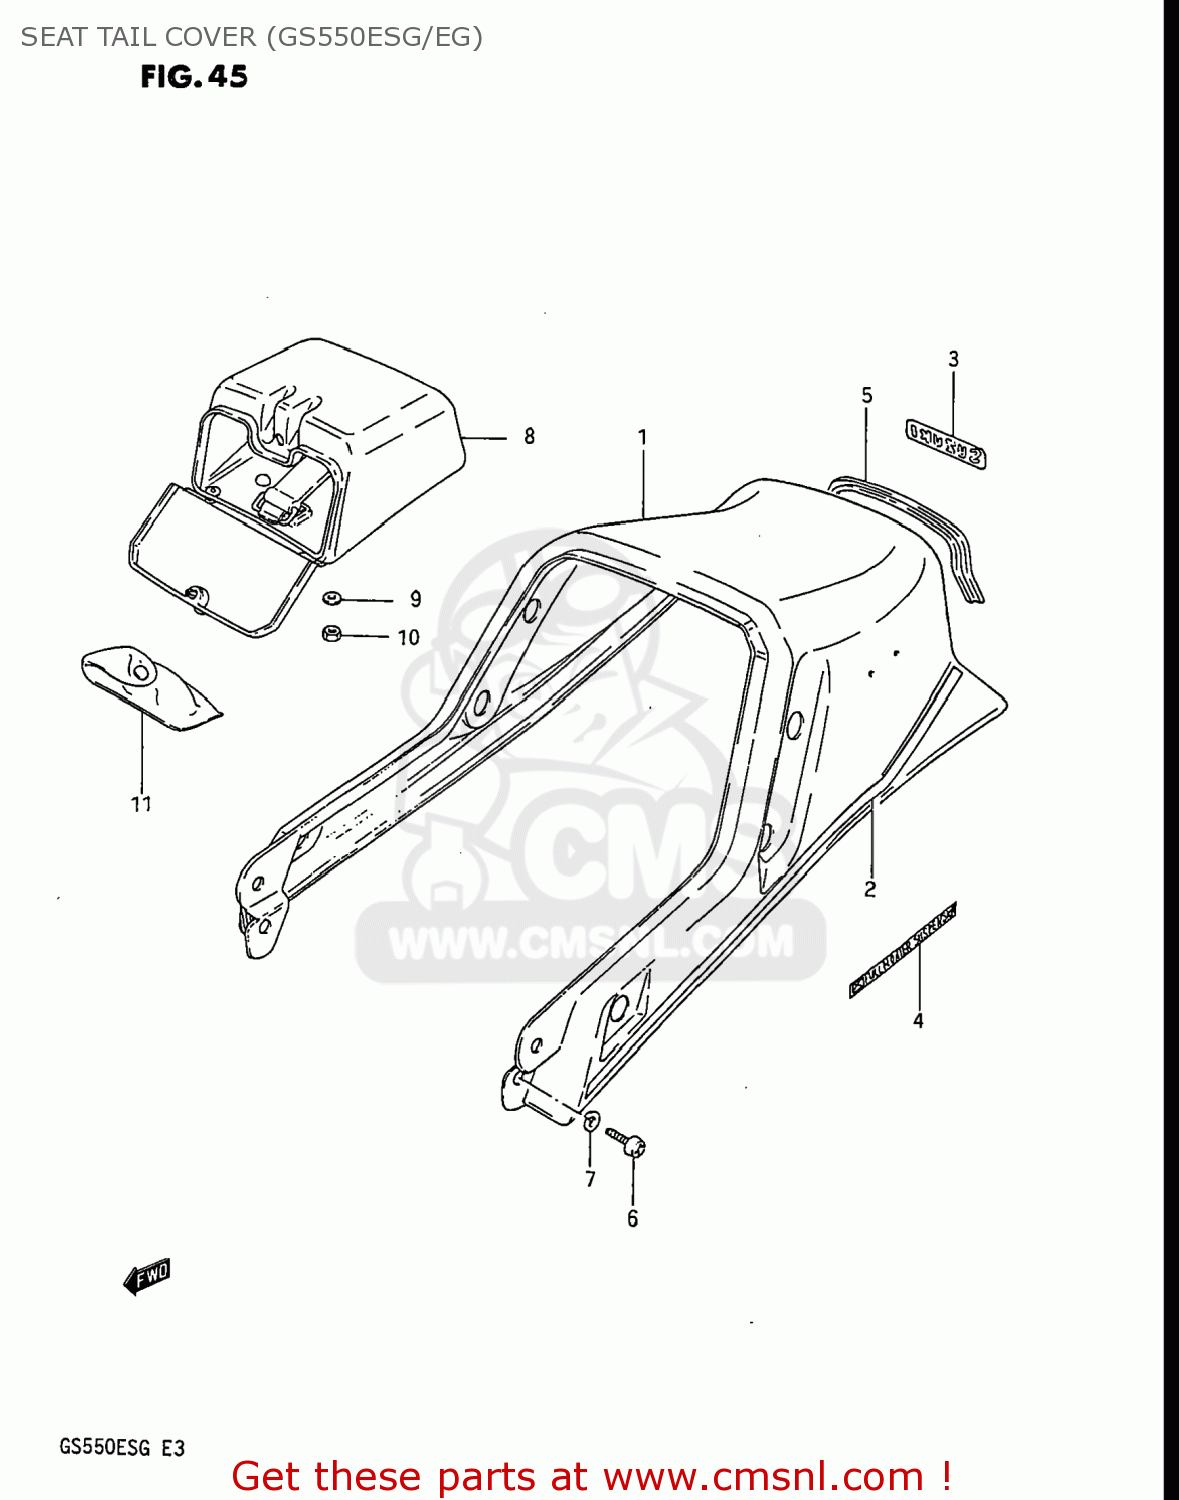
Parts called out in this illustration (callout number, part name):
1	COVER,SEAT TAIL
2	TAPE SET
3	EMBLEM(WHITE)
4	EMBLEM
5	BLIND,SEAT TAIL COVER
6	SCREW
7	WASHER,LOCK
8	BOX,SEAT TAIL
9	WASHER
10	NUT
11	TOOL ASSY
